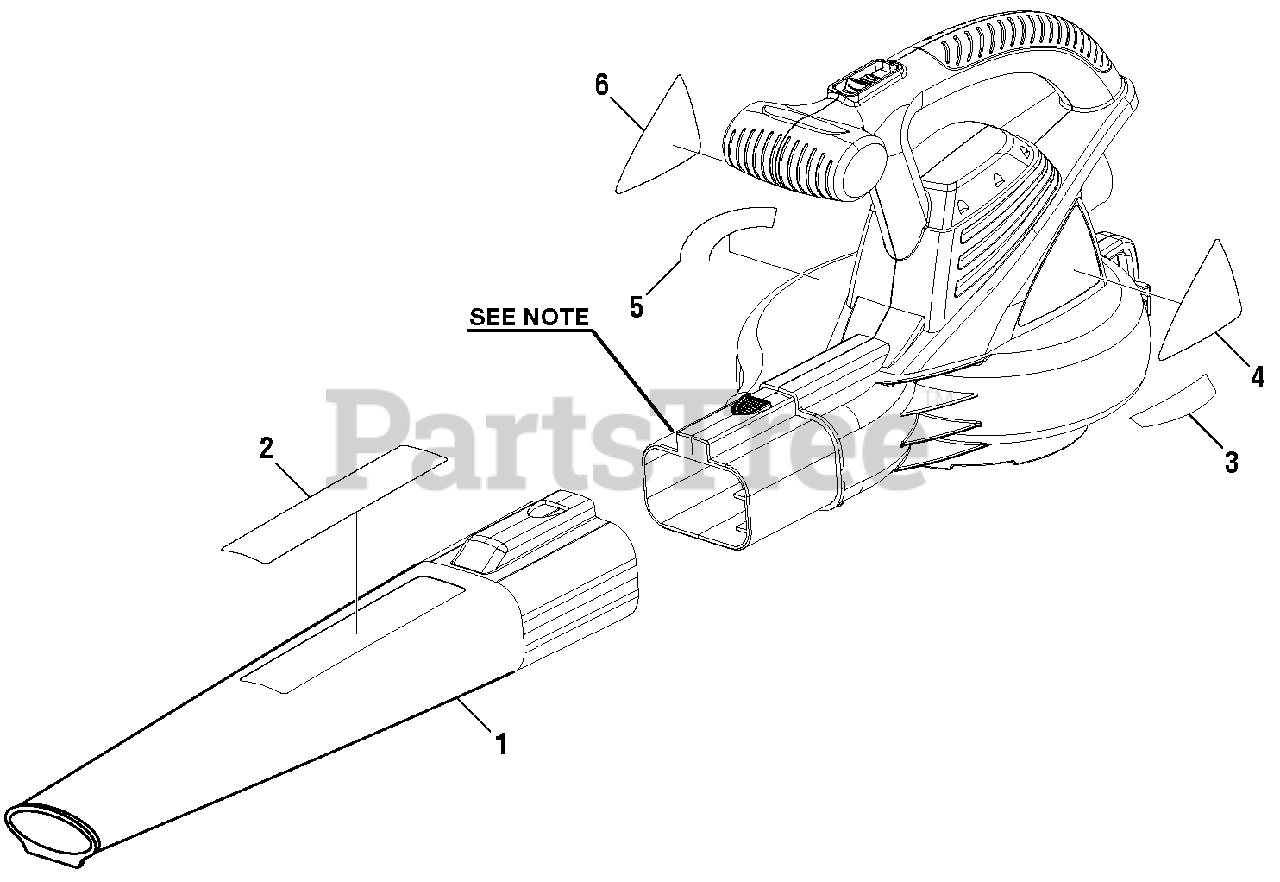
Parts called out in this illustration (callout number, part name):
1	Blower Tube
2	Blower Tube Label
3	Data Label
4	Logo Label (Motor Housing, Left)
5	Warning Icon/Performance Label
6	Logo Label (Motor Housing, Right)
